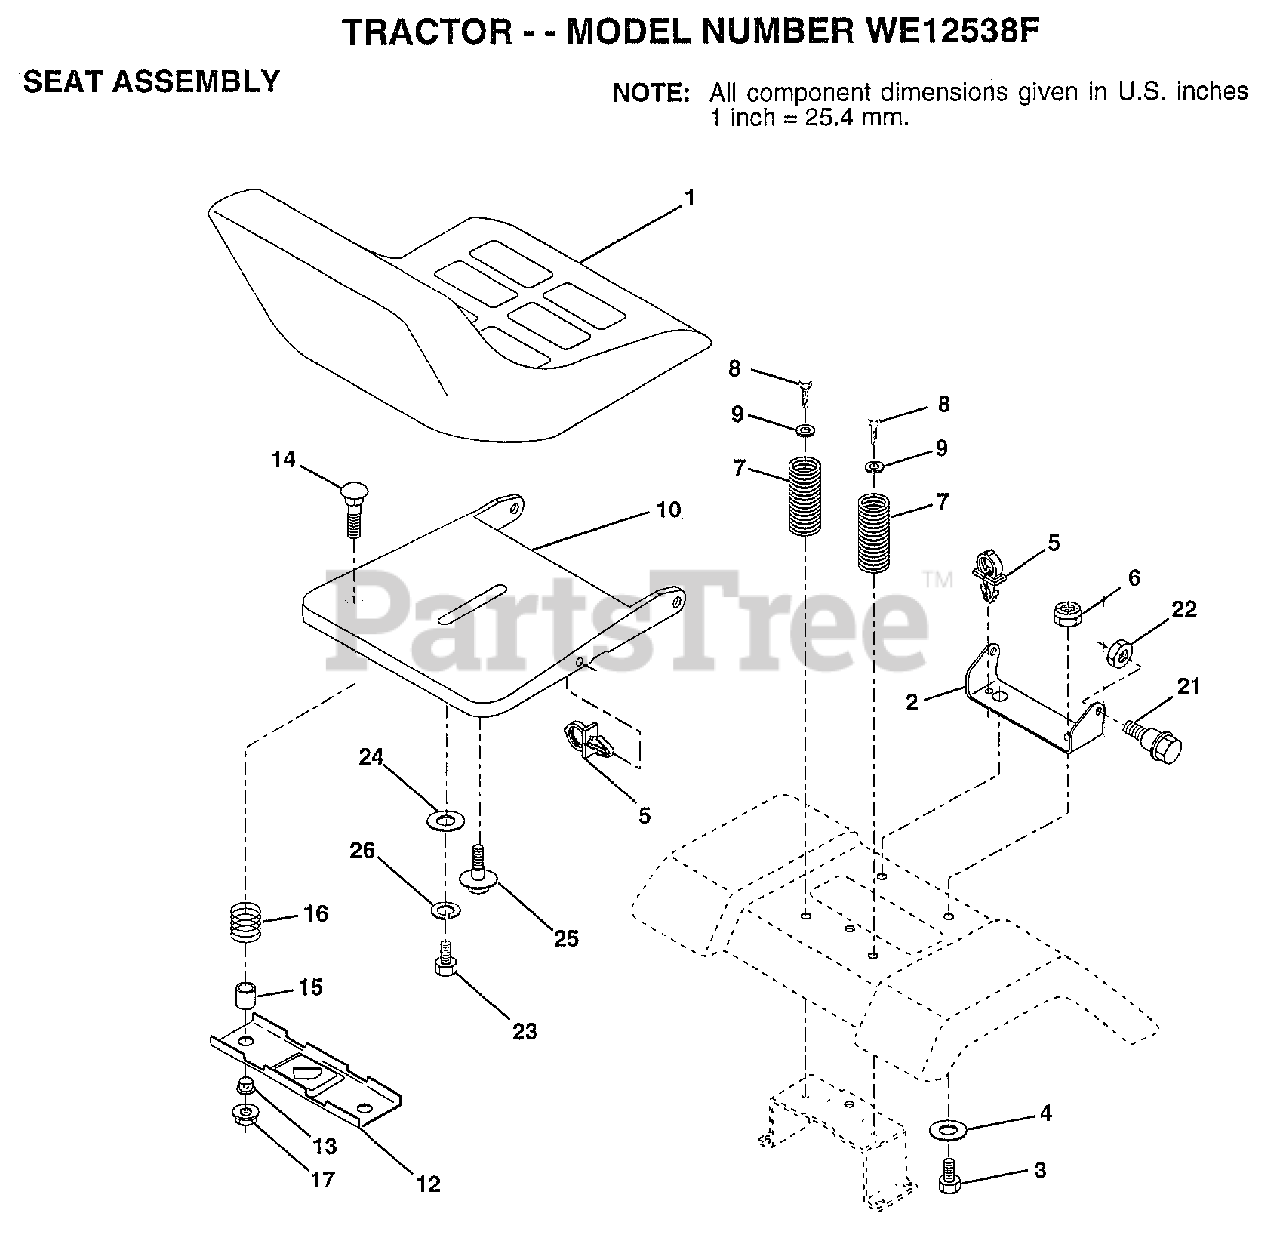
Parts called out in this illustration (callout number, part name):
2	BRACKET PVT SEAT
3	BOLT
4	WASHER PM
5	CLIP.PUSH-IN.HING
6	NUT
7	SPRING COMPRESSIO
8	SCREW GTV
9	WASHER
10	PAN-SEAT
12	BRKT SWITCH
13	BUSHING
14	BOLT-RD HD SQ NK
15	SPLIT SPACER
16	SPRING
21	"BOLT,SHOULDER"
22	NUT
23	BOLT
24	WASHER
25	"BOLT,SHOULDER"
26	LOCKWASHER
